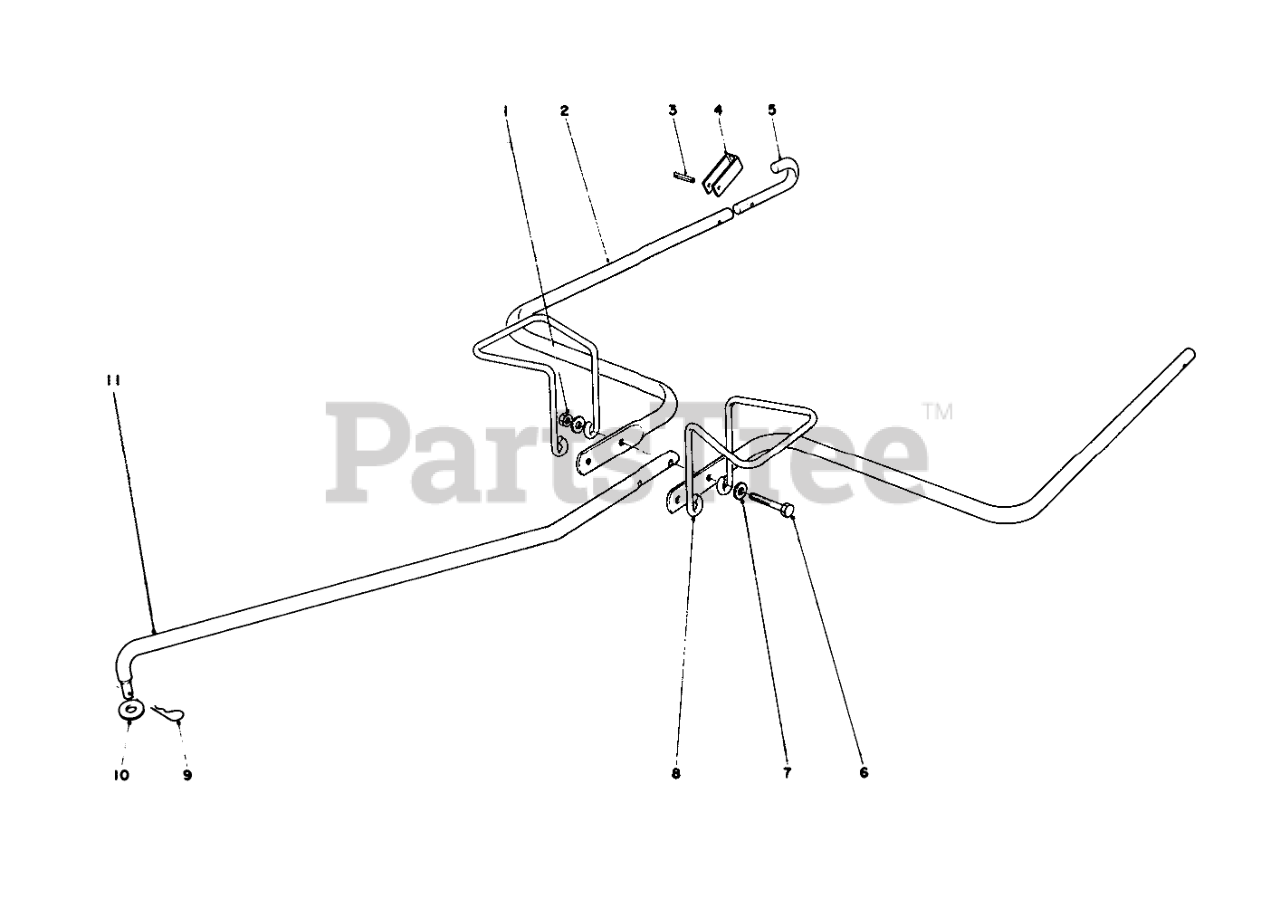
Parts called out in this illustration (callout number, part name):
1	NUT-LOCK, CONE
2	HITCH ARM
3	PIN-ROLL, SLOT
4	HITCH LOCK
5	HOOK HITCH ARM
6	SCREW-HH
7	WASHER-FLAT
8	Support Bag
9	PIN-COTTER
10	PUSH NUT
11	POLE HITCH
